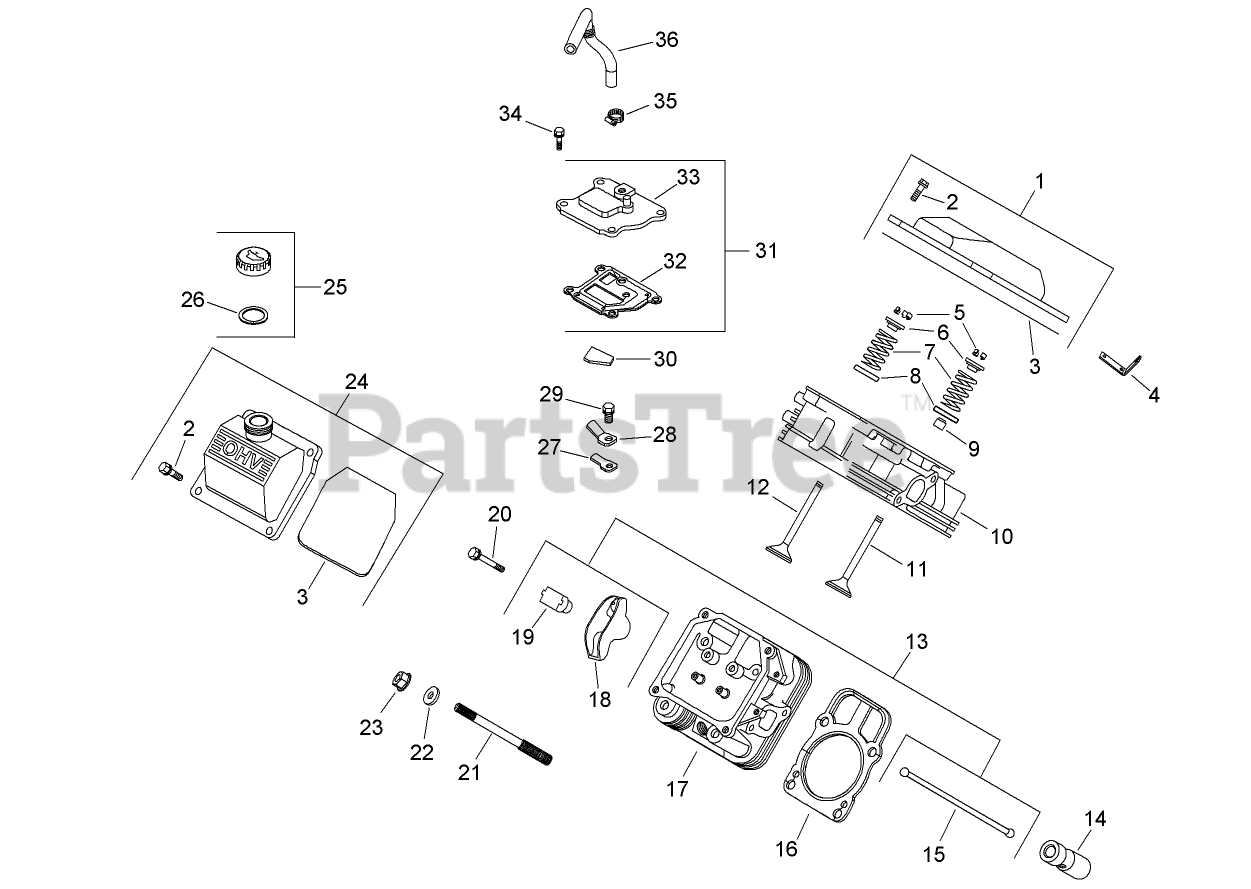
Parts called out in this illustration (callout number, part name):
1	Plain Valve Cover ASM (INCLUDES 2, 3)
2	SCREW-FLANGE (M6X1.0X30)
3	O-RING (VALVE COVER)
4	STRAP-LIFTING
5	RETAINER KIT
6	CAP-SPRING, VALVE
7	SPRING-VALVE
8	RETAINER-SPRING
9	SEAL-STEM, VALVE
10	No.1 CYLINDER HEAD ASM
11	VALVE-INTAKE (STD)
11	VALVE-INTAKE (.25)
12	VALVE-EXHAUST (STD)
12	VALVE-EXHAUST (.25)
13	VALVE TRAIN KIT (INCLUDES 15, 18, 19)
14	HYDRAULIC VALVE LIFTER KIT (INCLUDES 25 357 14-S)
15	ROD-PUSH
16	CYLINDER HEAD GASKET KIT
17	No.2 CYLINDER HEAD ASM
18	ARM-ROCKER
19	PIVOT-ARM, ROCKER
20	SCREW-FLANGE (M6X1.0X34)
21	STUD (M8X1.25xM10X1.5x105MM)
22	WASHER-FLAT (8.6 MM)
23	NUT-FLANGE (M8X1.25)
24	OIL FILL ROCKER COVER KIT (INCLUDES 2, 3)
25	OIL FILL CAP KIT (YELLOW) (INCLUDES 26)
26	O-RING (DIPSTICK)
27	REED-BREATHER
28	RETAINER-REED
29	SCREW-HHFTF (M5X.80X10)
30	FILTER-BREATHER
31	BREATHER ASM (INCLUDES 32, 33)
32	GASKET-BREATHER
33	COVER-BREATHER
34	SCREW-HHFTF (M6X1.0X20)
35	CLAMP-HOSE, SPRING (.25)
36	HOSE-BREATHER
